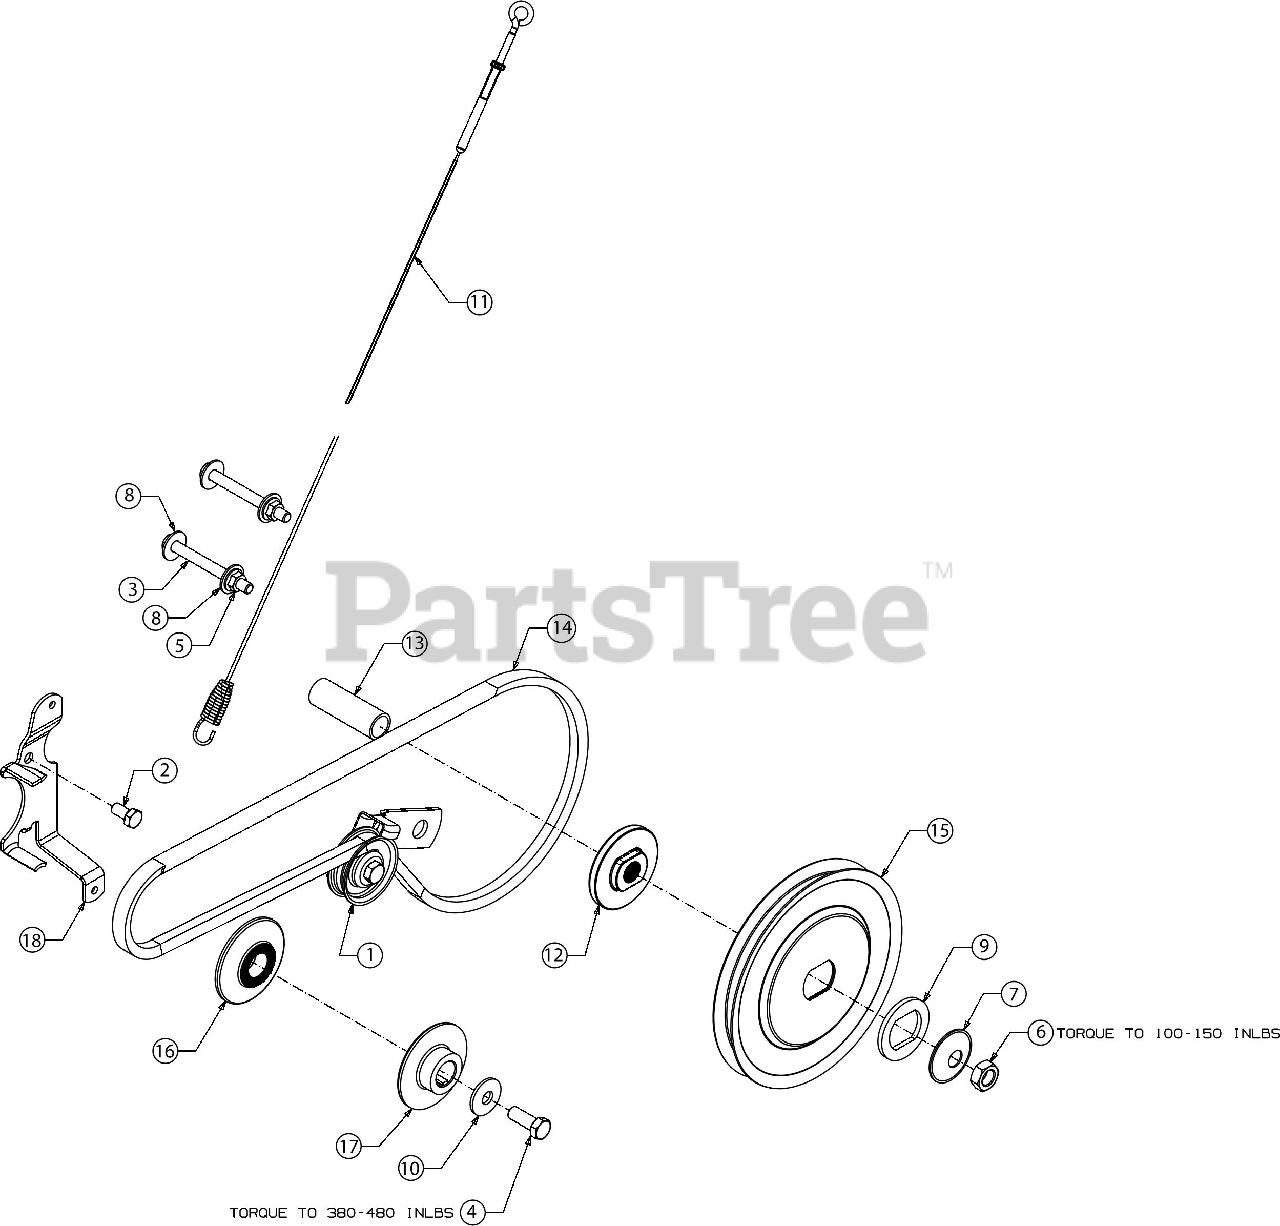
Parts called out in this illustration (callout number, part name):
1	IDLER BRACKET ASSEMBLY
1	SCREW 3/8-16 X 1.25 GR5
1	JAM LOCK NUT
1	IDLER PULLEY
1	IDLER BRACKET
1	BELT KEEPER
2	HEX SCREW 5/16-24 X .62
3	HEX SCREW 5/16-18 X 3.00
4	SCREW 3/8-24 X 1.00 GR8
5	FLANGE NUT 5/16-18
7	BELL WASHER .535 ID X1.50 OD X.052
8	BELL WASHER .337 X.867 X .057
9	RETAINING WASHER
10	BELL WASHER
11	FORWARD CLUTCH CABLE
12	PULLEY MOUNTING ADAPTER
13	SPACER
14	V-BELT
15	PULLEY
16	ENGINE PULLEY INNER HALF
17	ENGINE PULLEY OUTER HALF
18	BELT COVER BRACKET
